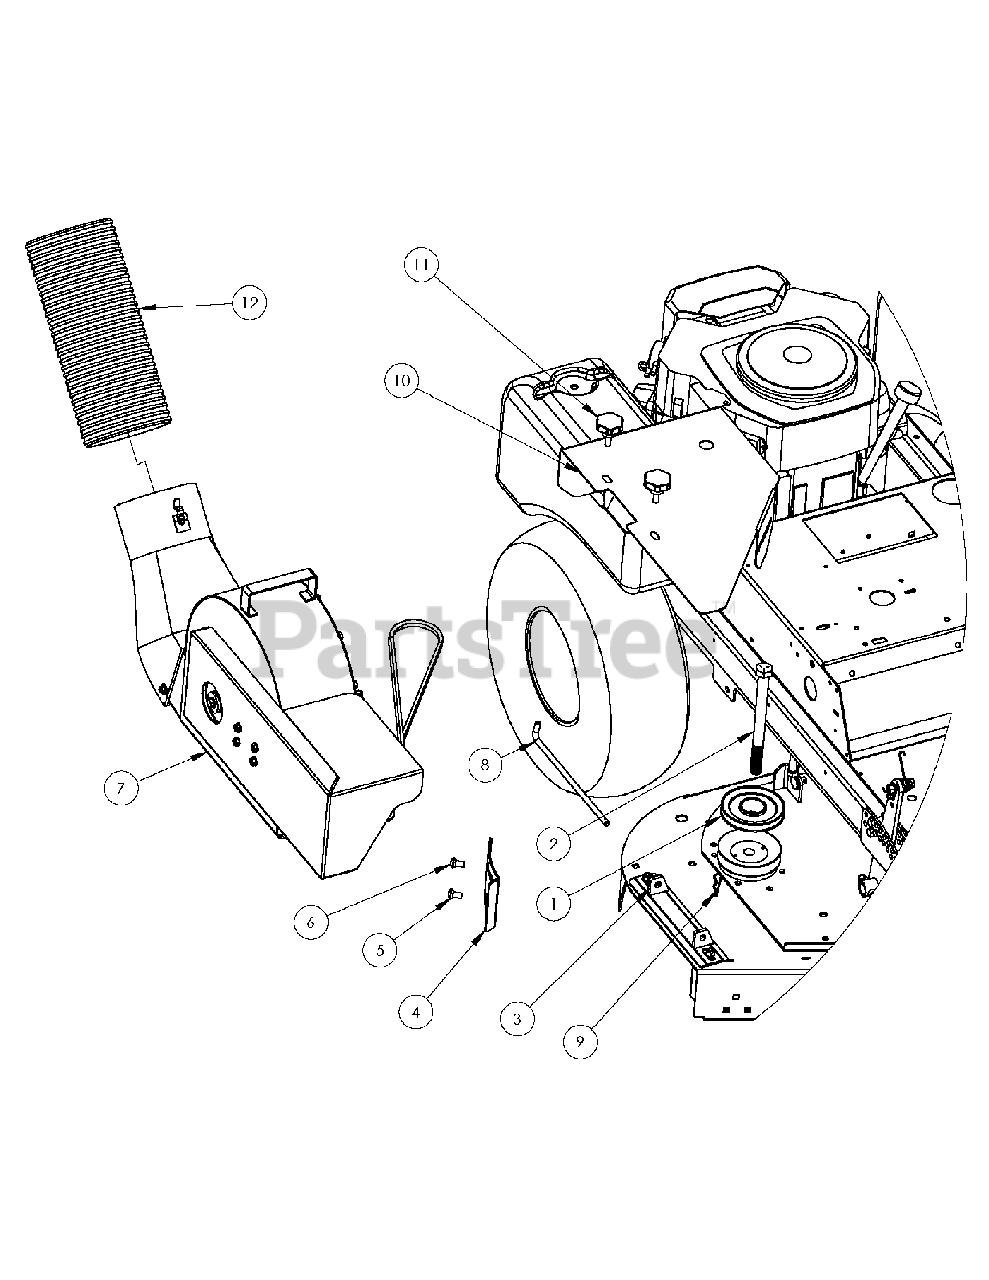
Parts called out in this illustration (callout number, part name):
1	CATCHER MOUNT
3	DECK MOUNTING ADAPTOR
4	DECK PLATE
6	CARRAGE BOLT, 3/8" - 16 X 1" LONG
8	MOUNTING PIN
10	BELT GUARD
11	MOUNTING KNOBS
12	DISCHARGE HOSE
